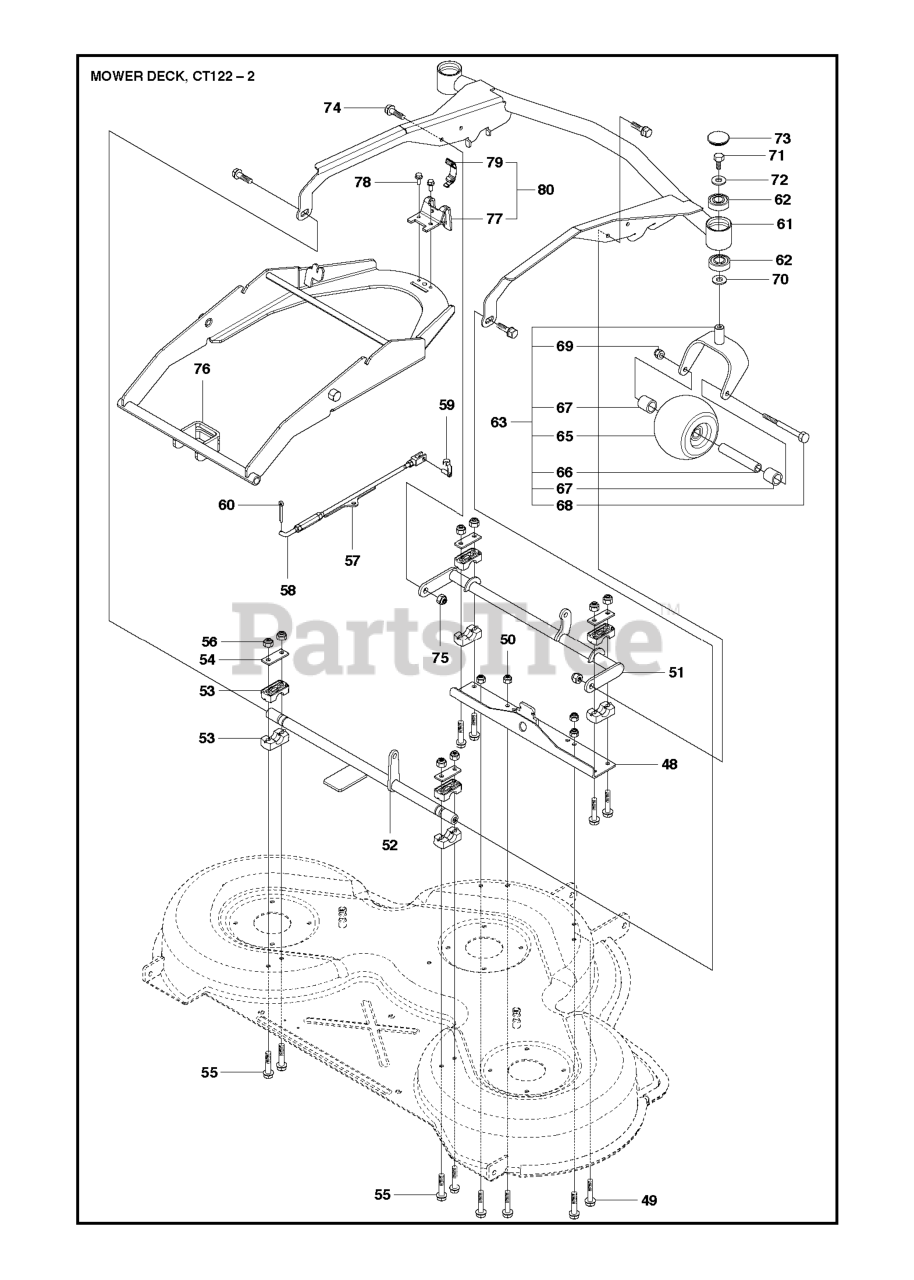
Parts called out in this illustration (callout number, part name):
50	LOCKNUT M8
56	LOCKNUT M8
58	PARALLEL ROD
62	BALL BEARING 6004-2RS1
63	PIVOT WHEELS
65	DECK ROLLER, FRONT
69	NUT
73	HUB CAP PIVOT WHEEL
75	LOCKNUT M8
78	SCREW
79	CLIP GRAY
